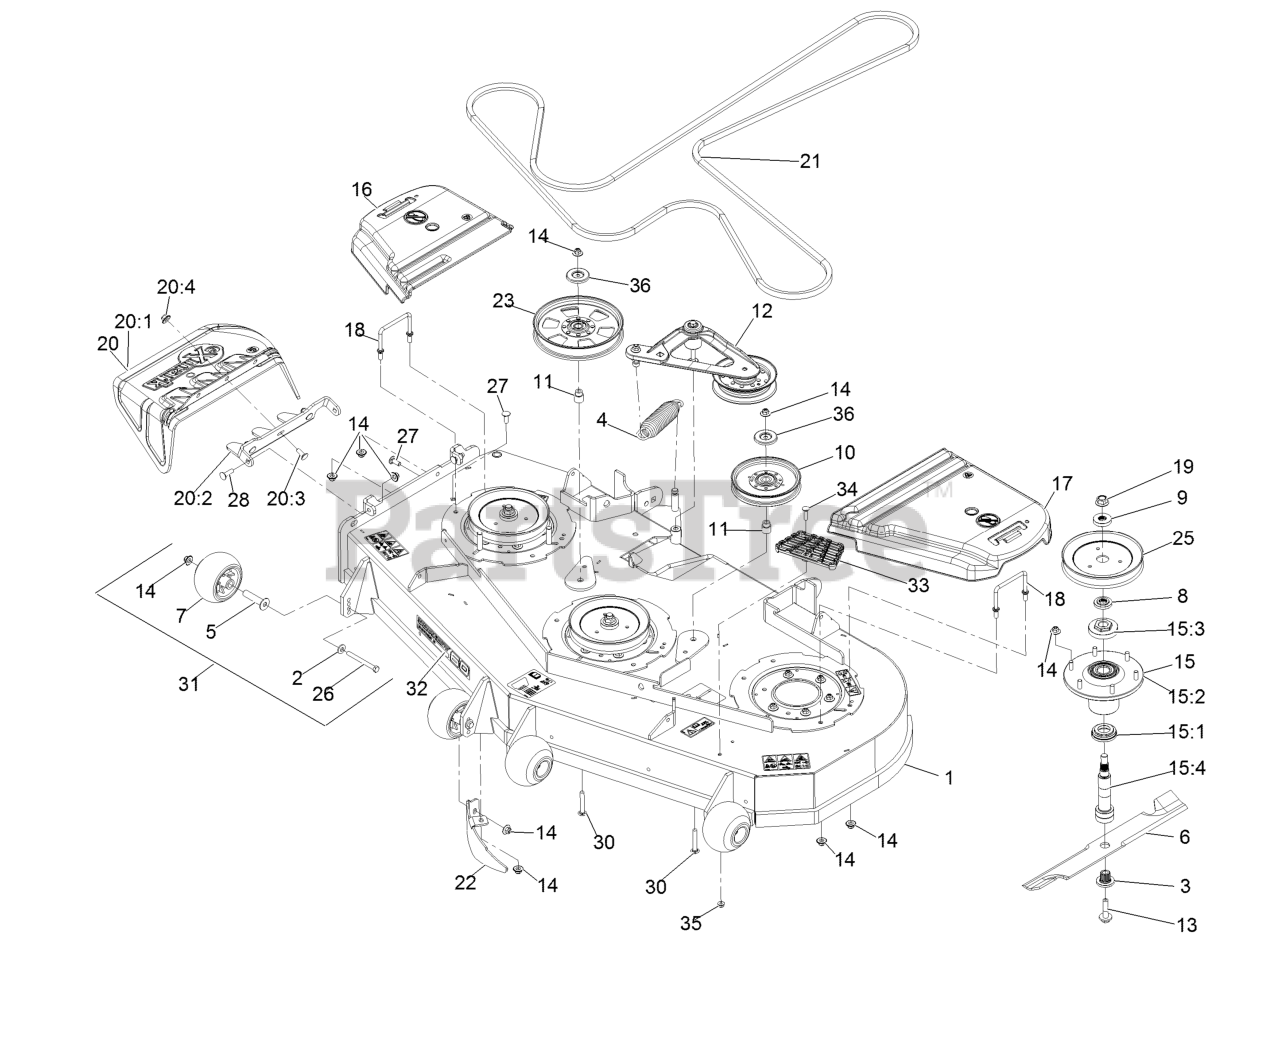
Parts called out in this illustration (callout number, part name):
1	Deck ASM,W/Decals 60
2	Washer-Spring Disc 3/8
3	Bushing, Splined
4	Spring-Extension
5	Axle, Roller
6	Blade, Solid
6	Blade, Low Lift
6	Blade, Mulching
6	Blade, Notched
6	Blade-Extreme 2, 20.50"
7	Roller-Anti-Scalp
8	Spacer, Splined Stepped
9	Spacer, Splined
10	Idler-Pulley
11	Bushing, Idler
12	Deck Idler ASM
13	Screw-Sems 1/2-20 X 2.19
14	Nut-Nyloc 3/8-16 Flg
15	ASM,Spindle Housing
15:1	Guard, Bottom
15:2	Asm, Cutter Housing
15:3	Nut, Spindle 7/8-14
15:4	Spindle,Double Spline
16	Cover-Belt, RH
17	Cover-Belt, LH
18	Wireform-Cover
19	Nut-Flange 5/8-18 Centerlock
20	ASM,Discharge Chute
20:1	Chute, Discharge
20:2	Bracket,Discharge Chute
20:3	Bolt-Carriage 3/8-16 X 1
20:4	Nut-Nyloc 3/8-16 Flg
21	Belt,V-5V-198.75
22	Dogleg - Lz60
23	Pulley-Idler, Flat
25	Sheave,Blade Drive 7.25
26	Screw-HH 3/8-16 X 3 3/4 GR 8
27	Bolt-Carriage 3/8-16 X 1
28	Bolt-Carriage 3/8-16 X 1 1/4
30	Bolt-Carriage 3/8-16 X 2 1/2
31	Kit, Anti-Scalp Roller
32	Decal, 606
33	Step-Deck
34	Bolt-Carriage 5/16-18 X 1 1/4
35	Nut-Nyloc 5/16-18 Flg
36	Shield-Dust
